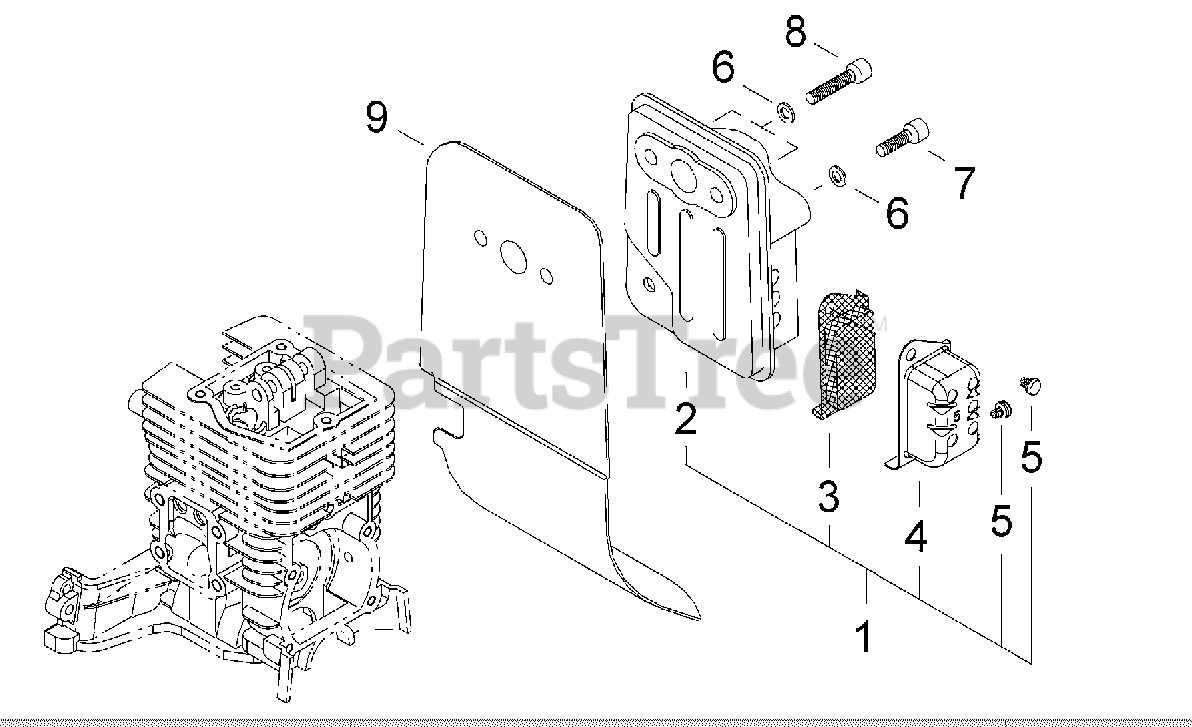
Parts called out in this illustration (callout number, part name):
1	MUFFLER ASSY
2	MUFFLER
3	SCREEN, SPARK ARRESTOR
4	GUIDE, EXHAUST
5	SCREW - 4X6
6	WASHER - 5
7	SCREW - 5X16
8	SCREW - 5X25
9	SHIELD, EXHAUST
